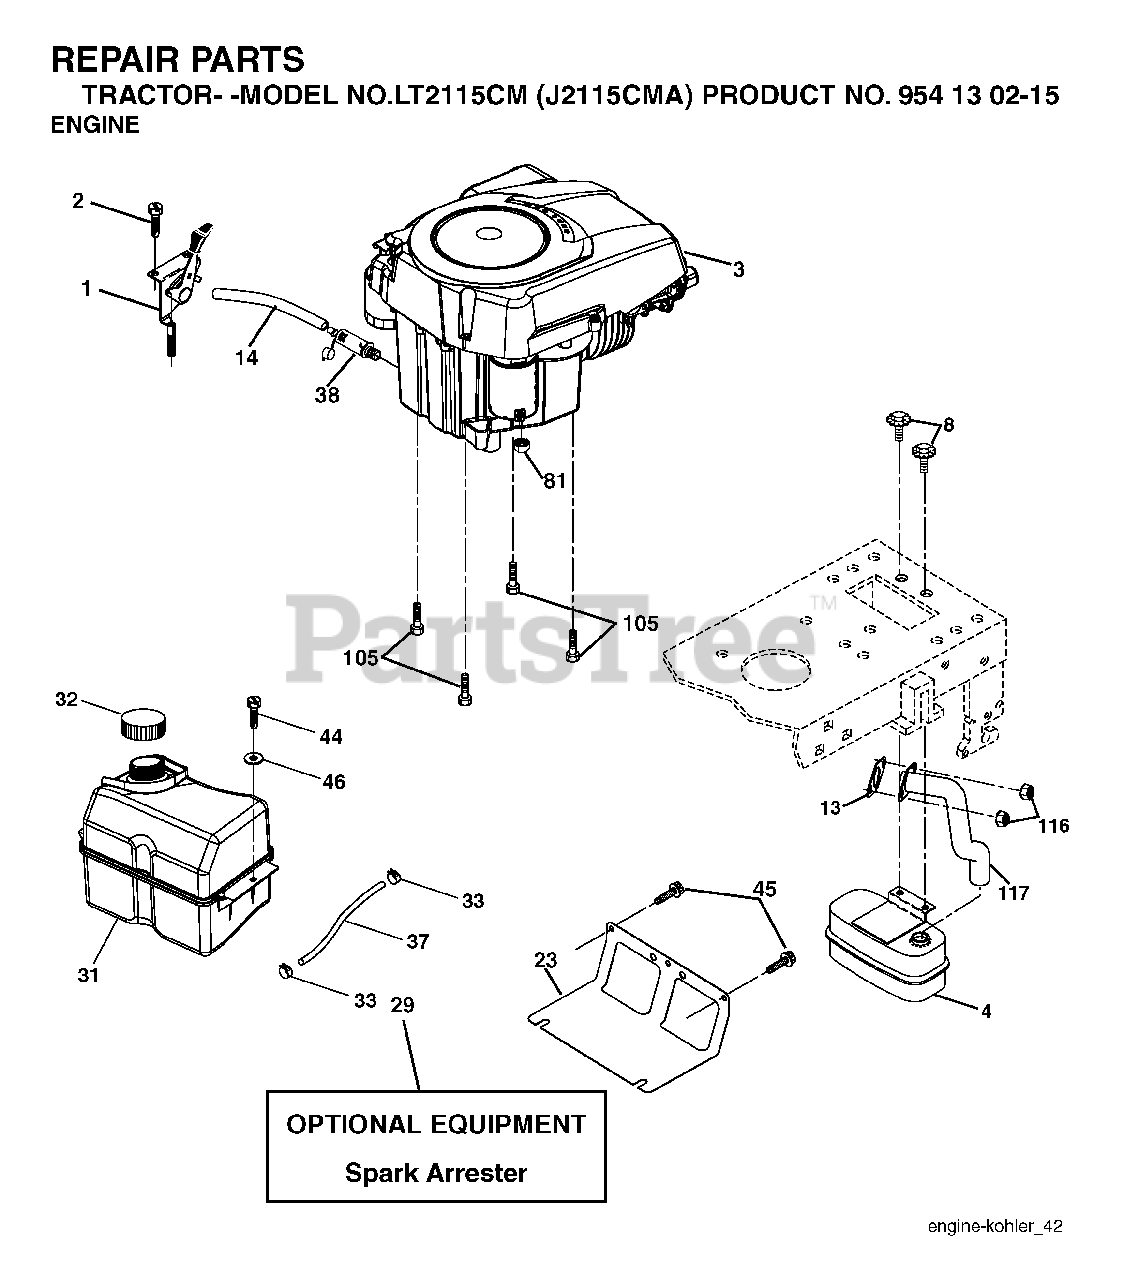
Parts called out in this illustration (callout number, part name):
1	CONTROL.THROTTLE.LT/YT
2	SCREW
4	MUFFLER.SINGLE.CYL.KOHL/B&S
8	BOLT, 5/16-18 X 1 3/4
13	GASKET ENGINE
14	TUBE, DRAIN OIL ASM.
23	SHEILD.BROWNING.DBR.GUARD
29	ARRESTER SPARK (OPTIONAL)
31	TANK FUEL
32	FUEL CAP
33	HOSE CLAMP
37	LINE.FUEL.20
38	PLUG DRAIN OIL EASY
44	SCREW HEXWSHR 1/4-20X3/4
45	SCREW, 3/8-16X3/4
81	NUT
105	SCREW 3/8-16X1
116	NUT.HEX.FLANGE.TOPLOCK
117	TUBE EXHAUST
